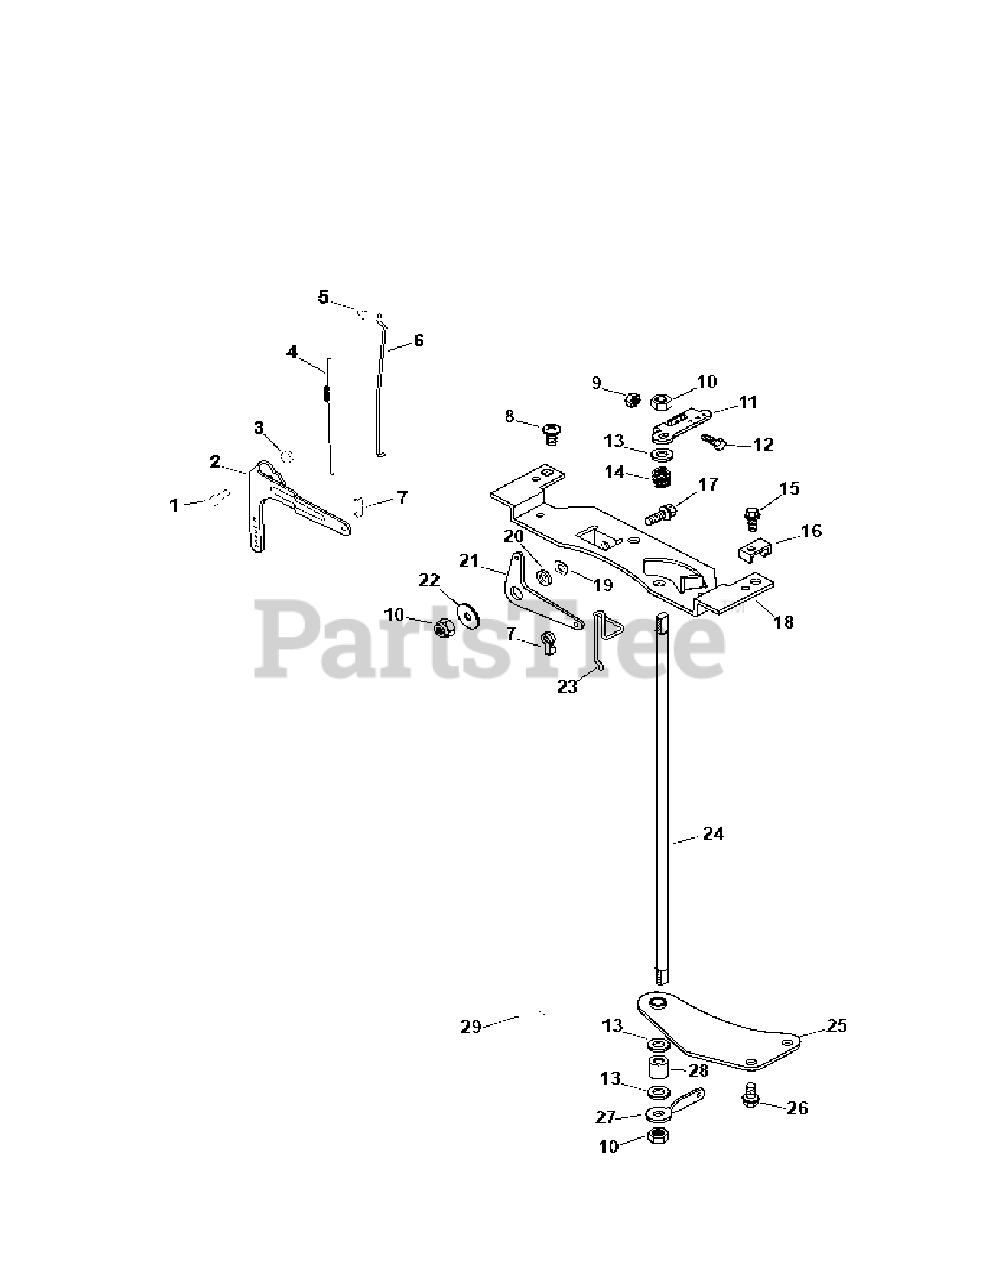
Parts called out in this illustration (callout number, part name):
1	Round Head Sq.Neck Bolt
2	Governor Lever
4	Linkage Spring
5	Linkage Retainig Bushing
6	Throttle Linkage
7	Linkage Retainig Bushing
11	Throttle Control Lever
14	Throttle Shaft Spring
15	Screw
16	Cable Clamp
17	Hex Flange Screw
18	Control Bracket
23	Choke Linkage
24	Throttle Shaft
25	Throttle Shaft Bracket
27	Throttle Control Lever
29	Governor Spring
